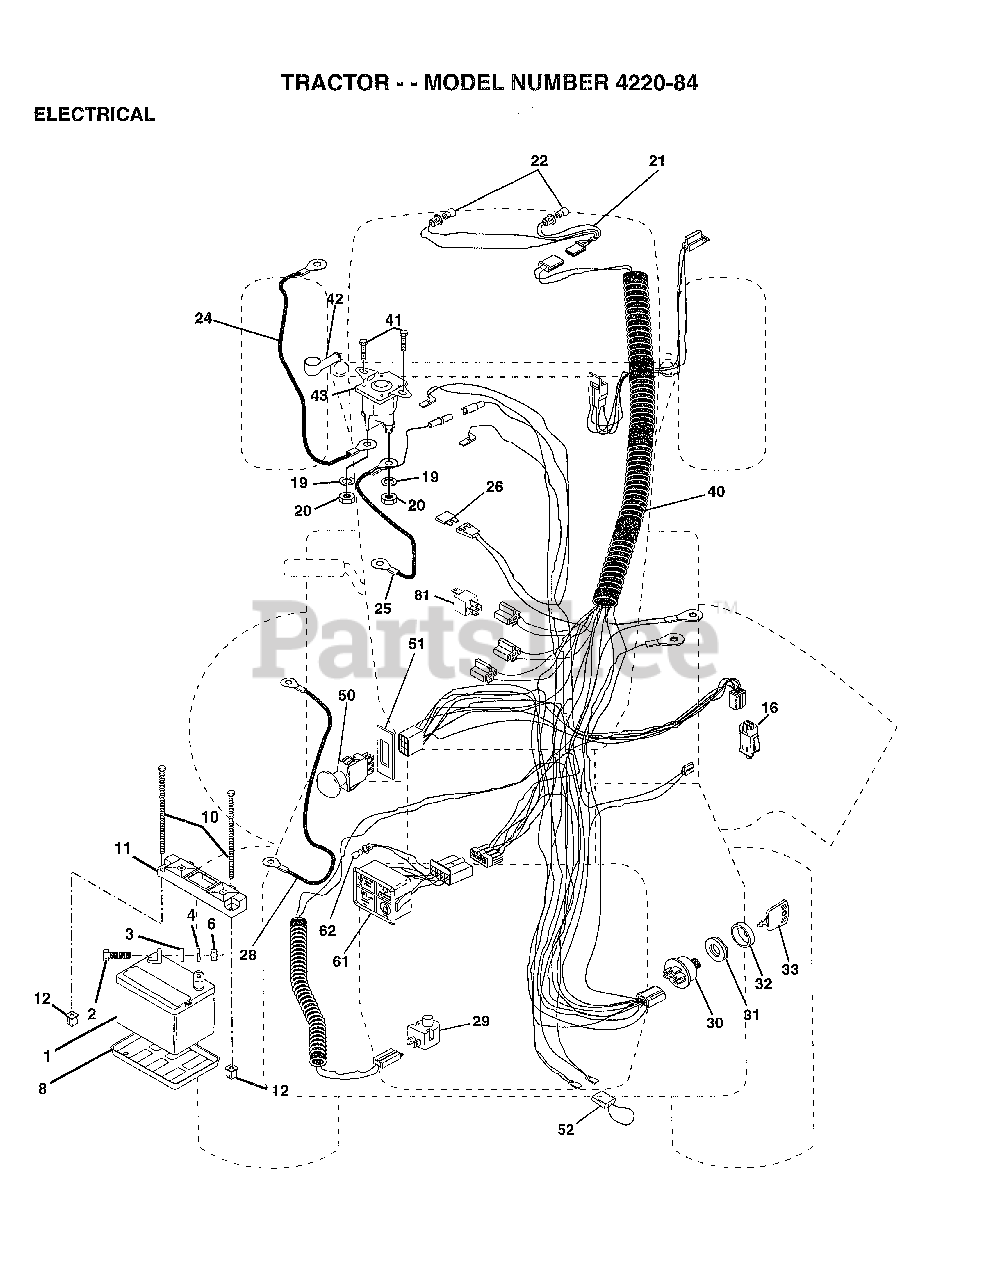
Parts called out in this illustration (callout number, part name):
3	LOCKWASHER
4	WASHER
8	"TRAY T, BATTERY"
11	HOLDDOWN BATTERY
16	SWITCH INTERLOCK
20	NUT
21	"HARNESS,LIGHT SOC"
22	HEADLAMP BULB
24	CABLE.BATY.22.RED
25	CABLE.BATRY.4GA.
26	FUSE HYT
28	"CABLE BATTERY,GRD"
29	SWITCH.PLUNGER
30	SWITCH IGN 4POS
31	NUT IGNITION
32	COVER KEY SWITCH
33	KEY
40	HARNESS.IGNITION
41	SCREW
50	PTO SWITCH.BLK
51	RING RETAIN PTO
52	PROTECTION LOOP
61	LIGHT.PKG.ASM.
62	BULB LIGHT T
81	RELAY ASSY T
